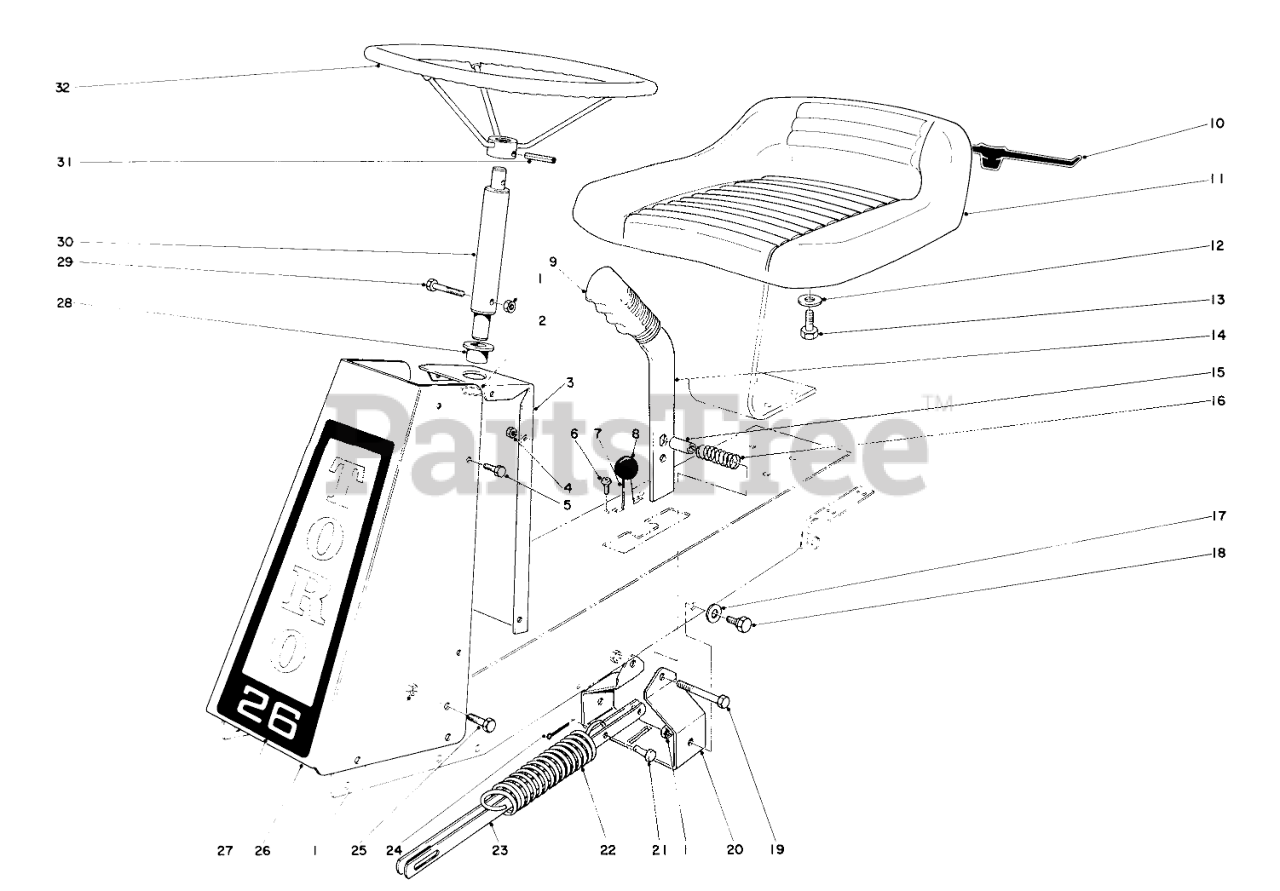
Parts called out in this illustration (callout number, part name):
1	Nut
2	Retaining Ring
3	Steering Column
4	NUT-LOCK
5	SCREW-HH
6	Screw
7	Throttle Control
8	Knob
9	Grip Handle
10	Decal
12	WASHER-FLAT
13	HEX HD CAPSCREW
14	Handle, Clutch
15	Spacer
16	Spring
17	WASHER-FLAT
18	Screw
19	SCREW-HH
20	Pivot
21	PIN-CLEVIS
22	Spring
23	Clutch Tie Bar
24	PIN-COTTER
25	SCREW-HH
26	Cover, Steering Column
27	Decal
28	Bushing
29	SCREW-HH
30	Steering Shaft
31	PIN-ROLL
32	Steering Wheel
